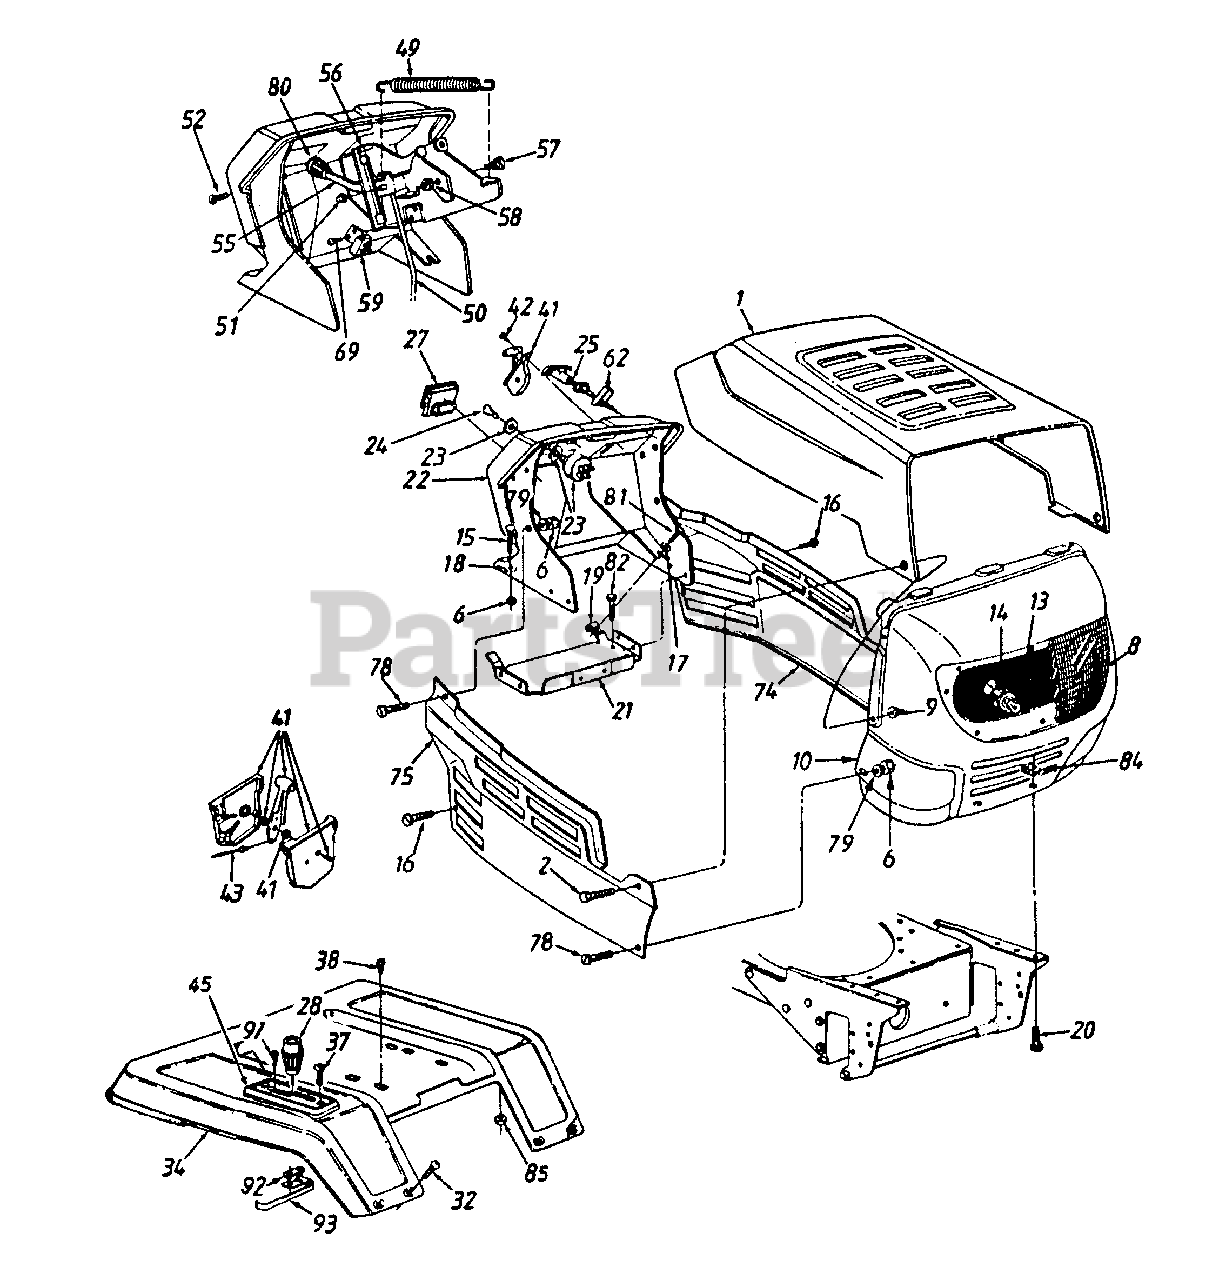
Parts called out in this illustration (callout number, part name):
6	Hex Nut 1/4-20 Thd.
8	Headlight Lens
9	Flange L-Nut 1/4-20 Thd.
13	Lamp
14	Socket
15	Carriage Bolt 1/4-20 x 1.0" Lg.
16	Hex Wash. Hd. TT-Tap Scr. 1/4-20 x .5" Lg.
17	Fl-Wash. .281" I.D. x .73" O.D.
18	Bolt Retainer 1/4" I.D.
19	Speed Nut 1/4-20 Thd.
20	Hex Bolt 5/16-18 x .75" Lg.
23	Ignition Switch
24	Ignition Key
25	Choke Control
27	Ammeter
28	Shift Knob
32	Carriage Bolt 1/4-20 x .5" Lg.
38	Hex Wash. Hd. AB-Tap Scr.5/16 x .75" Lg.
41	Throttle Box Ass'y.
42	Truss Mach. AB-Tap Scr. #10 x.5" Lg.
43	Throttle Control Wire 35" Lg.
45	Selector Plate
49	Ext. Spring 5.06" Lg.
50	Deck Control Rod
51	Speed Nut 1/4" Rod
52	Torx Mach. Scr. 1/4 x .62" Lg.
55	PTO Lever
58	Hex L-Nut 5/16-18 Thd.
59	Safety Switch
62	Retainer Clip
69	Hex Wash. Hd. B-Tap Scr.#10 x .38" Lg.
79	Bell-Wash. 1/4" I.D.
80	Knob
81	Hex TT-Tap Scr. 1/4-20 x .75" Lg.
82	Hex AB-Tap Scr. 1/4 x .62" Lg.
84	U-Nut 5/16-18 Thd.
85	Hex Sems Nut 1/4-20 Thd.
91	Hex Wash. Hd. AB-Tap Scr.#8 x .5" Lg.
92	Insulator Nut Plate
93	Reverse Safety Switch
